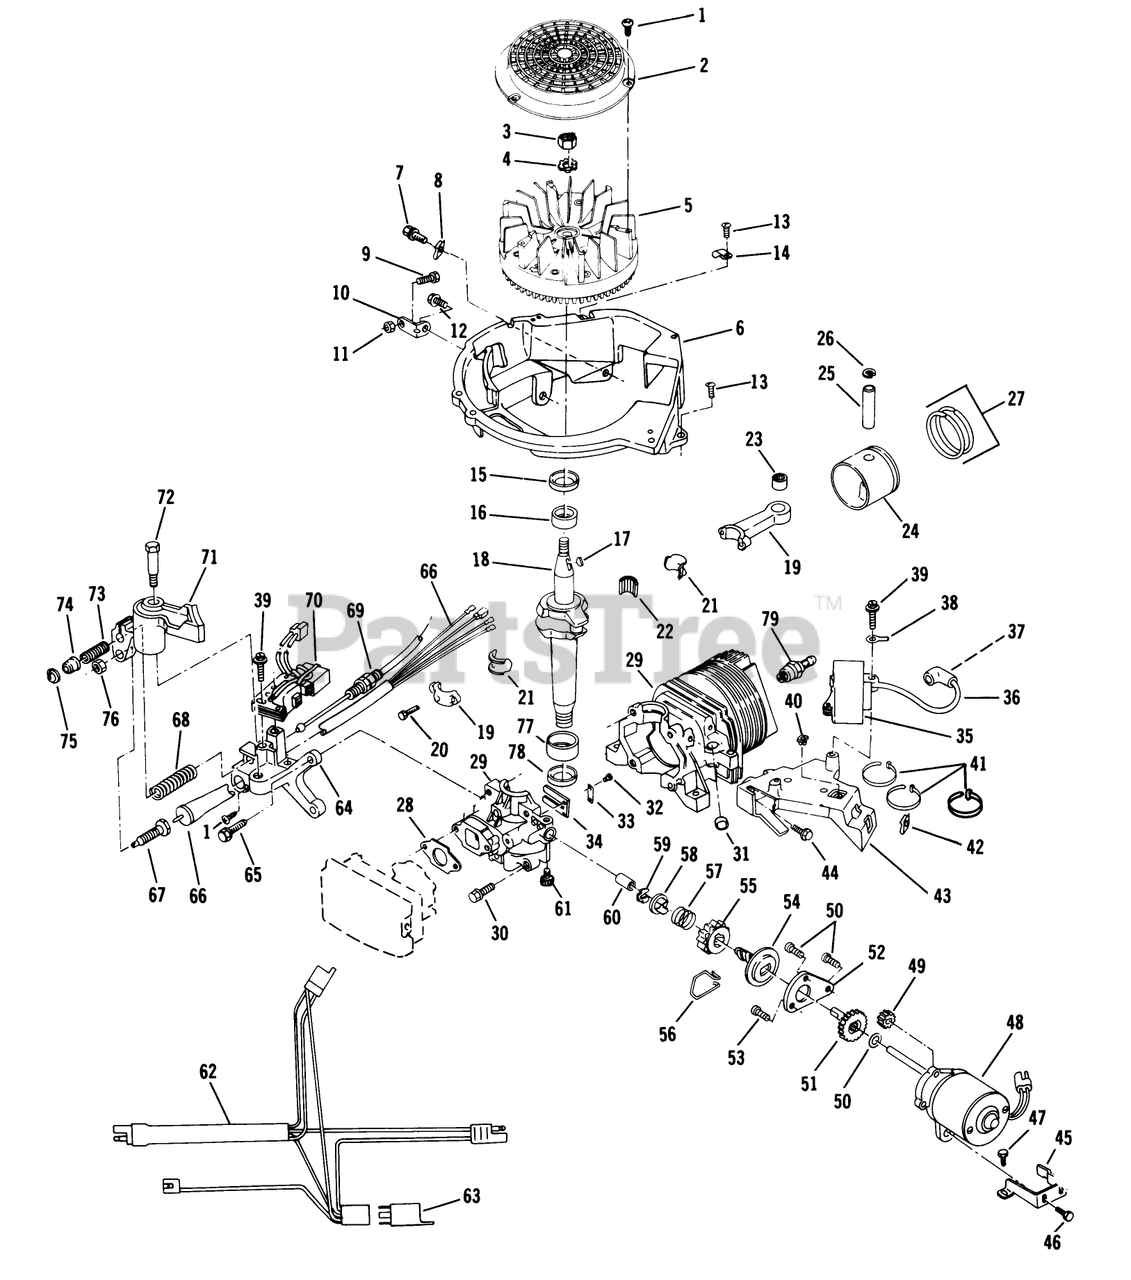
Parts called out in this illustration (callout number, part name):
1	SCREW F
2	SCREEN F'WHEEL S
6	BASE SHROUD F
7	SCREW-SEMS
11	NUT-LOCK F
13	SCREW F
16	BEARING V
20	SCREW-HSH
21	LINER ASM
23	BEARING AY F
26	RING-RETAINING
28	GASKET CARB S
30	SCREW S
31	PLUG-CORE VF
33	PLATE-BACKUP, REED
36	HT LEAD&COVER XEV
38	TERMINAL S
40	NUT-CLIP
42	NUT - SPEED S
45	BRACKET
49	*PINION EF
51	GEAR-DRIVEN
53	SCREW EF
55	PINION EF
56	SPRING F
57	*SPRING PINION EF
59	RET.RING EF
60	SLEEVE F
64	BRACKET F
67	PLUNGER S
68	SPRING-BRAKE
74	ACTUATOR-LEVER, BRAKE
75	RETAINER S
77	BEARING V
78	SEAL-OIL
